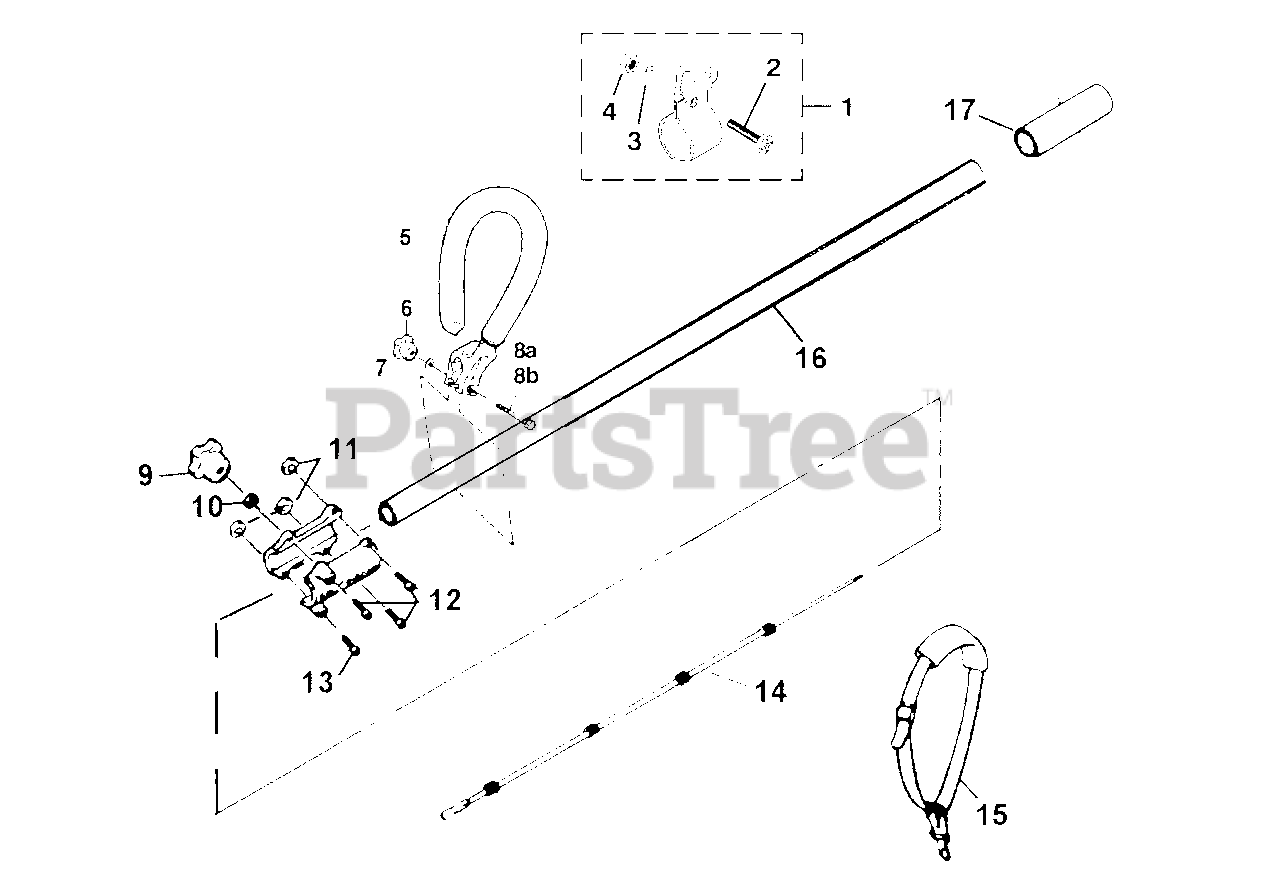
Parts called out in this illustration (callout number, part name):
1	HANGER ASSY.
5	HANDLE ASSY.
7	WASHER
8A	BOLT, HEX HEAD
8B	CARRIAGE BOLT
12	BOLT
14	LINER ASSY.
15	HARNESS
16	TUBE ASSY.
